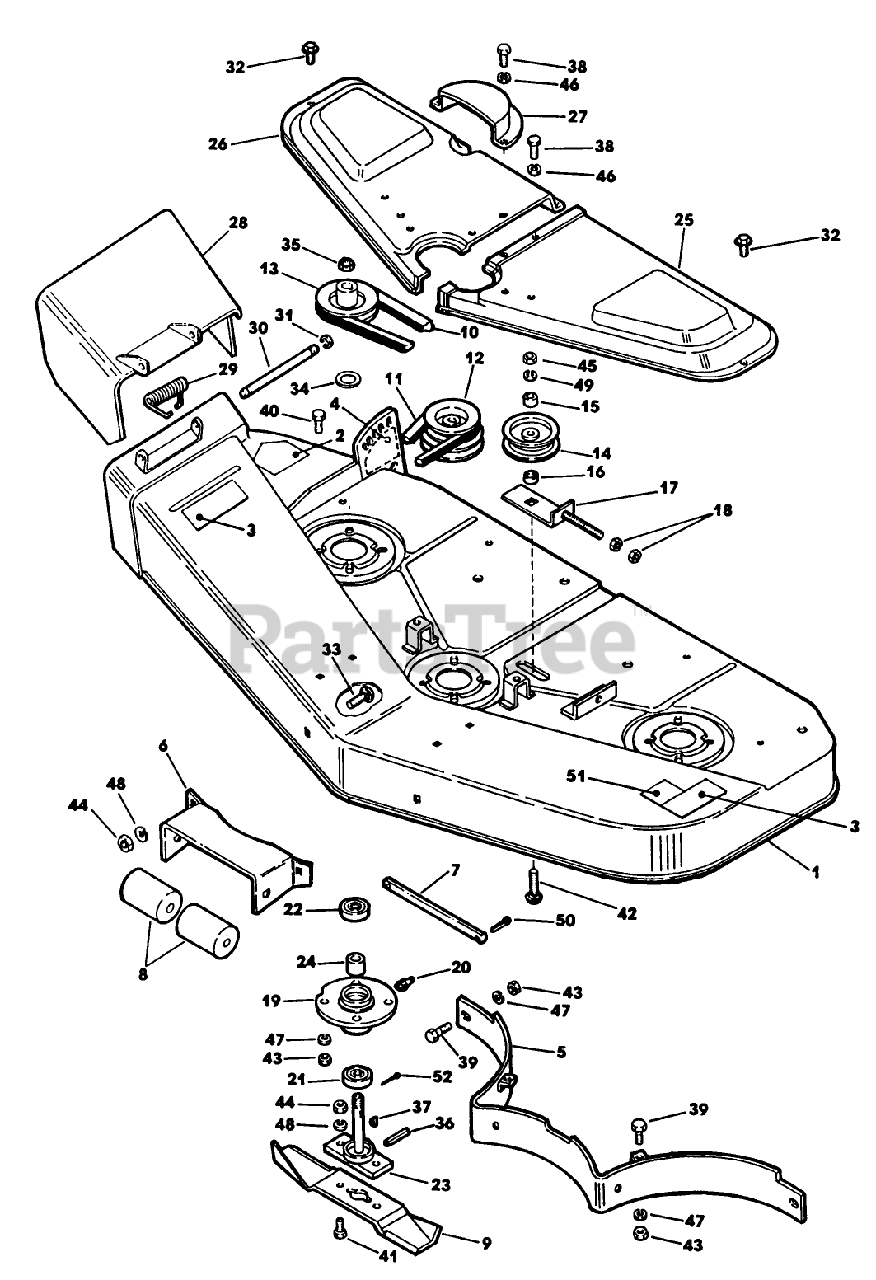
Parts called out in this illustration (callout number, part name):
1	HSG & DECAL (TRK)
3	DECAL
7	SHAFT
8	ROLLER
10	V-BELT (DECK)
10	V-BELT
14	PULLEY - IDLER
15	SPACER
19	HOUSING,SPINDLE S
23	SPINDLE ASSEMBLY *N/P
26	COVER AY - RH
30	SHAFT - CHUTE
31	E-RING
32	SCREW-THREAD FRMG
33	BOLT - CARRIAGE
34	SPACER
35	NUT-BLADE SPINDLE
38	SCREW-HH
39	SCREW - HEX
40	SCREW
42	BOLT
43	NUT SS
44	NUT
45	NUT - HEX JAM
48	WASHER
49	WASHER
